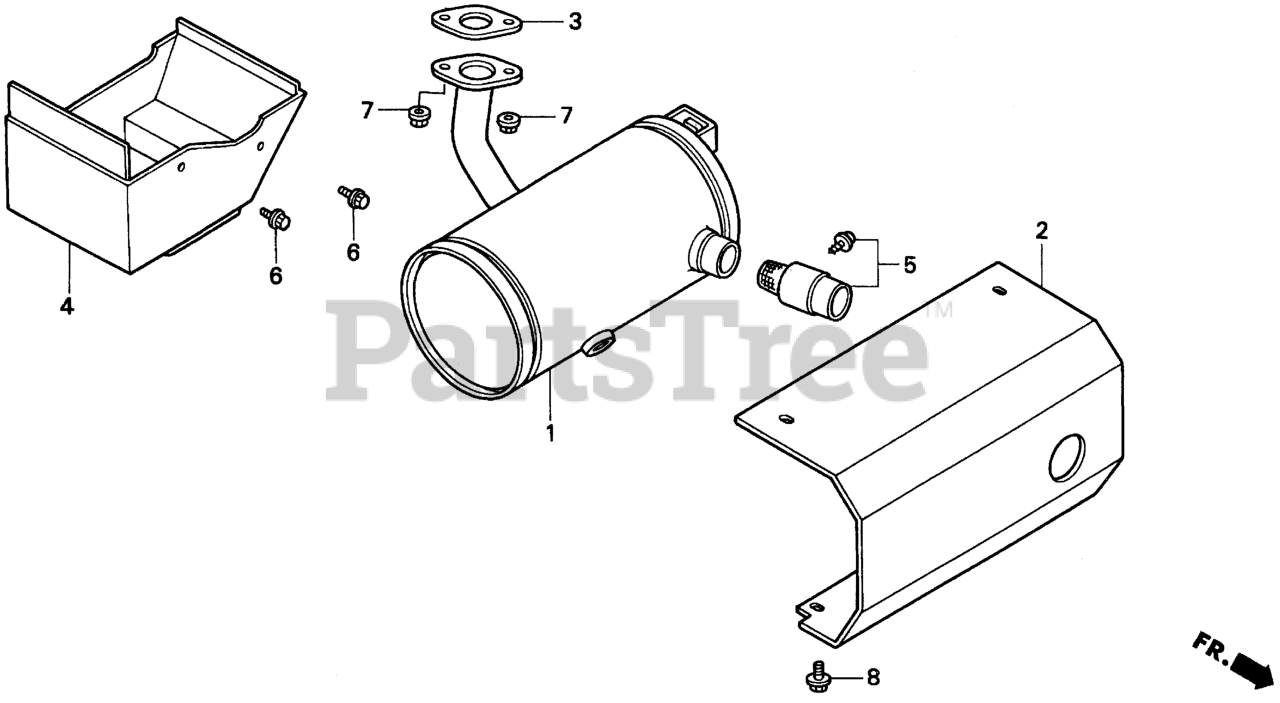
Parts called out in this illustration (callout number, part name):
1	MUFFLER, EX.
2	PROTECTOR, MUFFLER
3	GASKET, EX. PIPE Use up to Engine SN 2949254.
3	GASKET, EX. PIPE (WACKER)
4	PROTECTOR, HEAT (LOWER)
5	ARRESTER, SPARK
6	BOLT, FLANGE (6X12) (CT200)
7	NUT, FLANGE (8MM)
8	BOLT, FLANGE (8X12)
